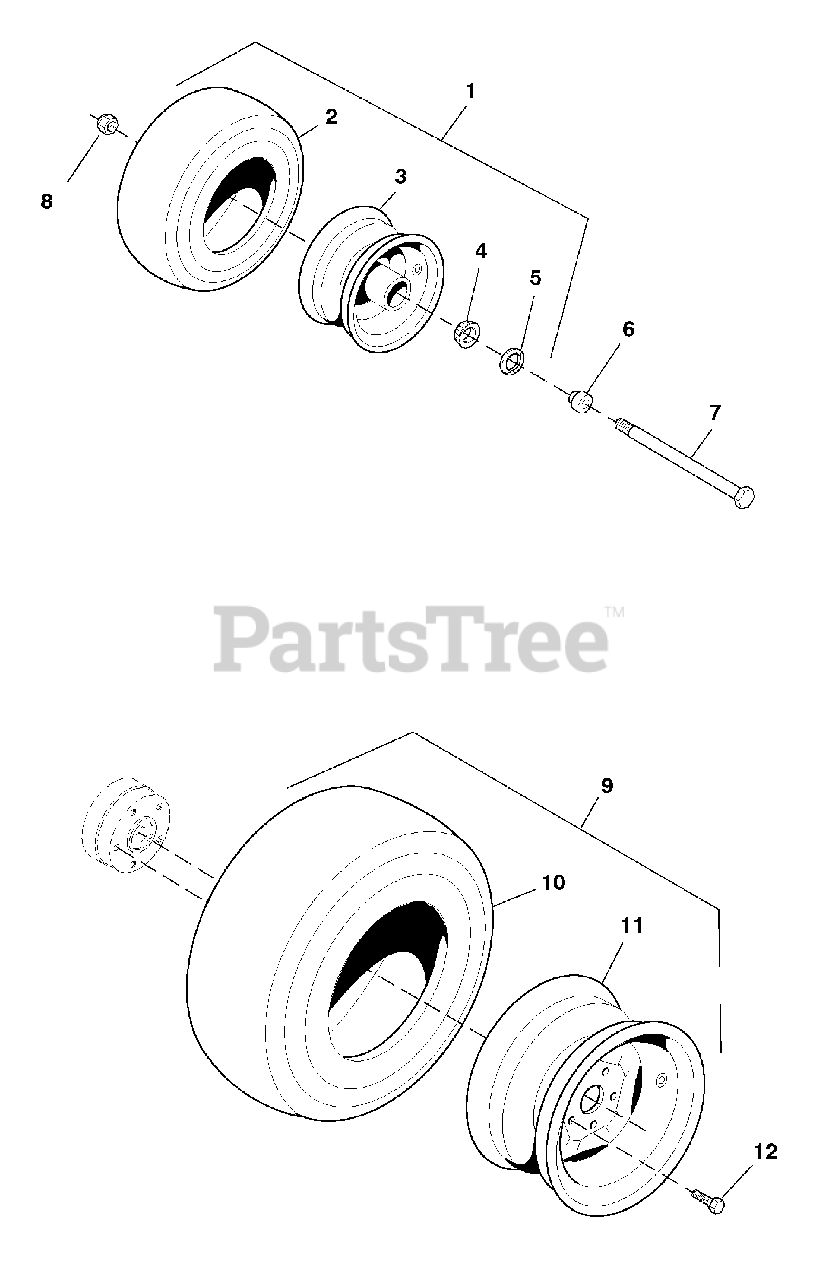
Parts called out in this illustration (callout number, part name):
1	WHEEL & TIRE ASSEMBLY, Front, 13 x 5.0 x 6, Complete
2	TIRE, Front, 13 x 5.0 x 6
3	WHEEL ASSEMBLY, Front, for 13 x 5.0 x 6 Tires, Complete
4	BEARING, TAPERED CONE
5	SEAL, GREASE
6	ADAPTER, Caster Wheel (2 per tire)
7	CAPSCREW, Hex Hd, 1-2/13 x 7-1/2
8	NUT, Hex, Nylon Lock, 1-2/13
9	WHEEL & TIRE ASSEMBLY, Rear, 23 x 9.5 x 12, Complete (Includes Ref 10 & 11)
10	TIRE, Rear, 23 x 9.5 x 12
11	WHEEL ASSEMBLY, Rear, for 23 x 9.5 x 12 Tires
12	WHEEL LUG, 1/2 x 1-5/8
